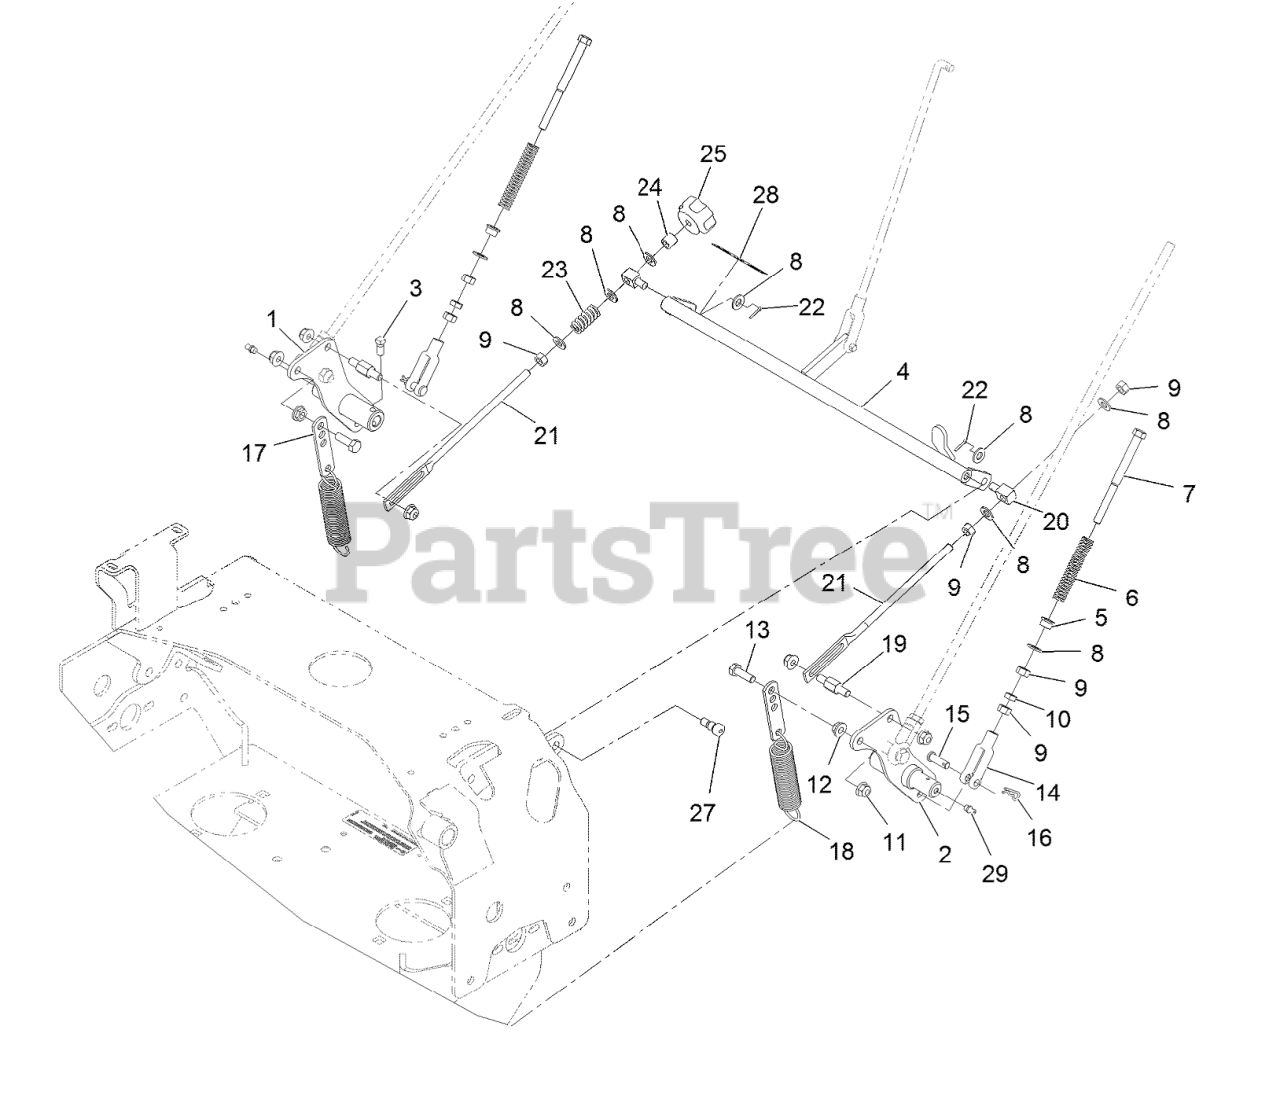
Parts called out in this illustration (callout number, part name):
1	WELD, MOTION CONTROL, RT
2	WELD, MOTION CONTROL, LT
3	SCREW-SET
4	WELD, SPEED CONTROL
5	BUSHING-FLANGED
6	SPRING,COMPRESSION (NEUT)
7	BOLT-RETURN, NEUTRAL
8	WASHER-PLAIN
9	NUT-HEX
10	NUT-JAM
11	NUT-HF, NI
13	SCREW-HH
14	YOKE-ADJUSTABLE
15	PIN-CLEVIS
16	PIN-COTTER
17	TAB-SPRING, EXTENSION
18	SPRING-EXTENSION
19	PIN, MOTION CONTROL
20	SWIVEL-ADJUSTABLE, SHORT
21	LINK-CONTROL, SPEED
22	PIN-COTTER
23	SPRING-COMPRESSION
25	KNOB-TRACKING
27	SCREW-HSH
28	DECAL-TRACKING ADJUSTMENT
29	FITTING-GREASE
